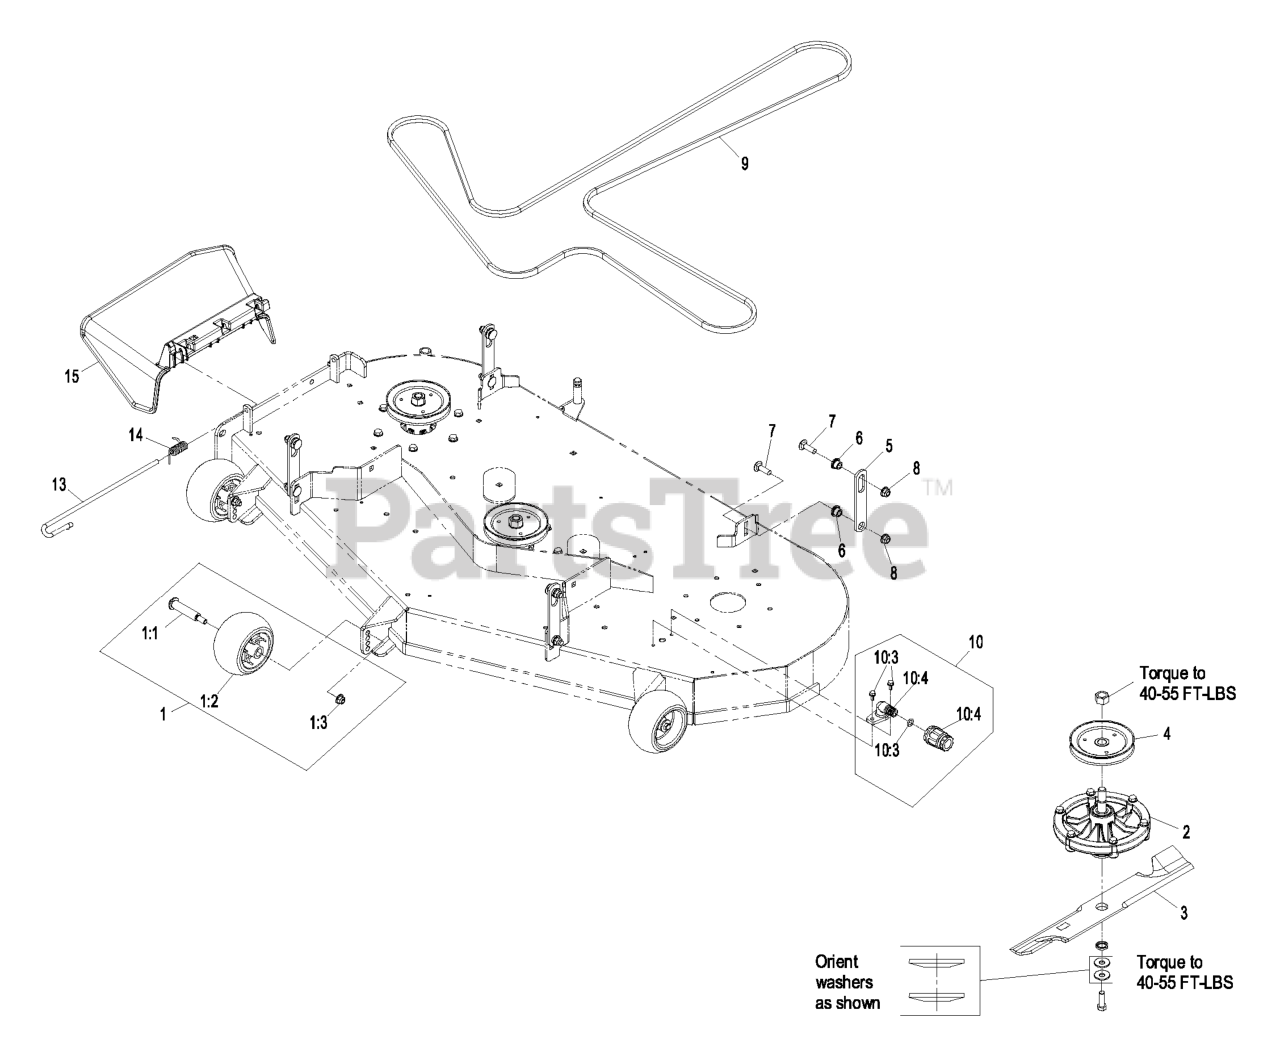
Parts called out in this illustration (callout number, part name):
1	ANTI-SCALP ROLLER KIT
1:1	BOLT-SHOULDER
1:2	ROLLER-SCALP, ANTI
1:3	NUT-HF, NI
5	HANGER-DECK
6	SPACER-STRUT
7	Bolt-Carriage 3/8-16 X 1 1/4
8	NUT-HF, NI
9	BELT
10	WASHOUT PORT KIT
10:3	SCREW-HWH
10:4	CONNECTOR-HOSE
14	SPRING-TORSION
15	CHUTE DEFLECTOR XRK M056
